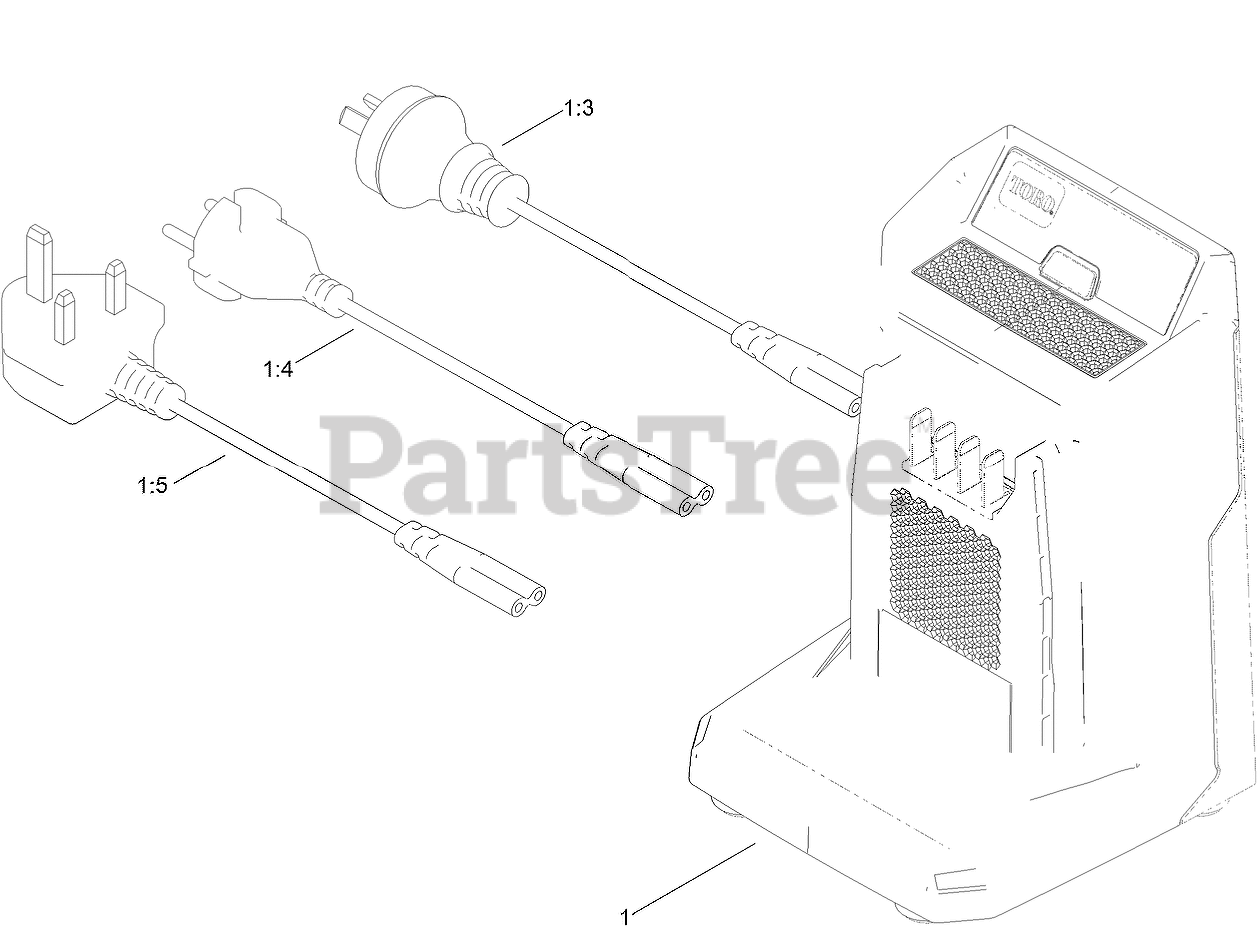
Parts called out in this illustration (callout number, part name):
1:3	CORD-CHARGER, AU/NZ
1:4	CORD-CHARGER, CE
1:5	CORD-CHARGER, UK
